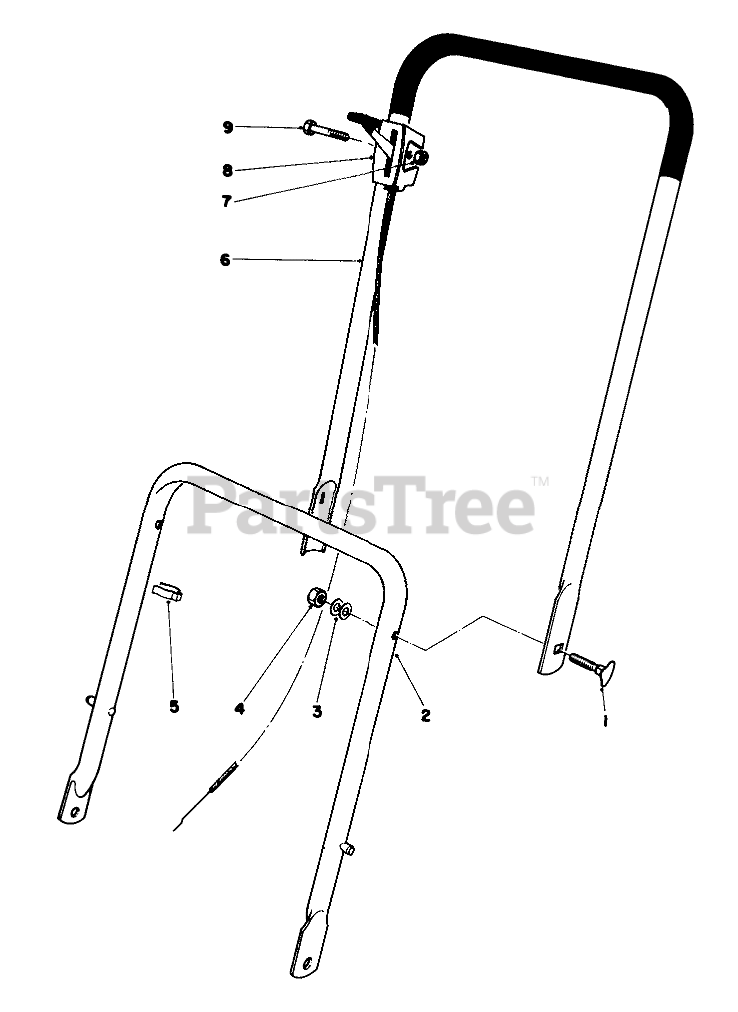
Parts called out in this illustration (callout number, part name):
1	HANDLE SCREW
2	Lower Handle
3	WASHER-PLAIN
4	NUT-LOCK, CONE
5	BOWDEN CLIP
6	Handle Upper
7	NUT-LOCK, CONE
8	THROTTLE CONTROL
9	SCREW-HH
